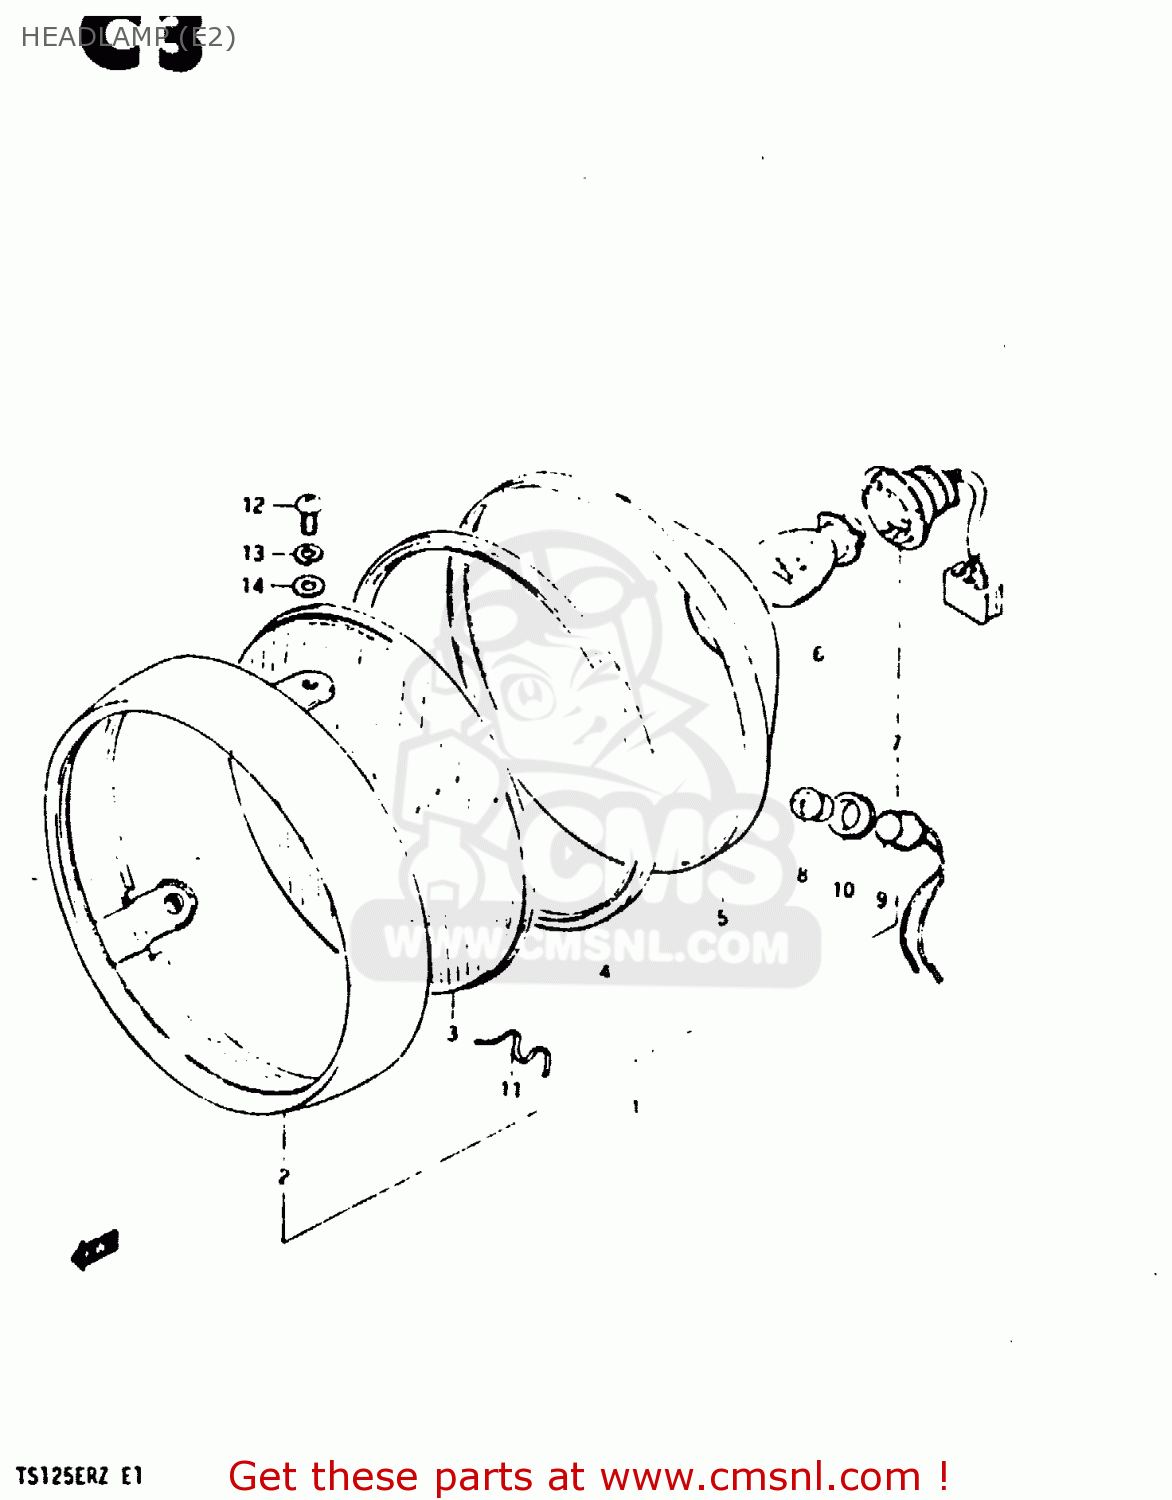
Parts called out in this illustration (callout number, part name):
1	HEADLAMP ASSY
2	RIM
3	LENS
4	GASKET (NAS)
5	REFLECTOR
6	BULB 12V35/35W
7	SOCKET
8	BULB(12V3.4W,STANLEY,A72A)
9	SOCKET
10	SEAL,PARKING BULB
11	SPRING
12	SCREW
13	LOCK WASHER
14	WASHER
